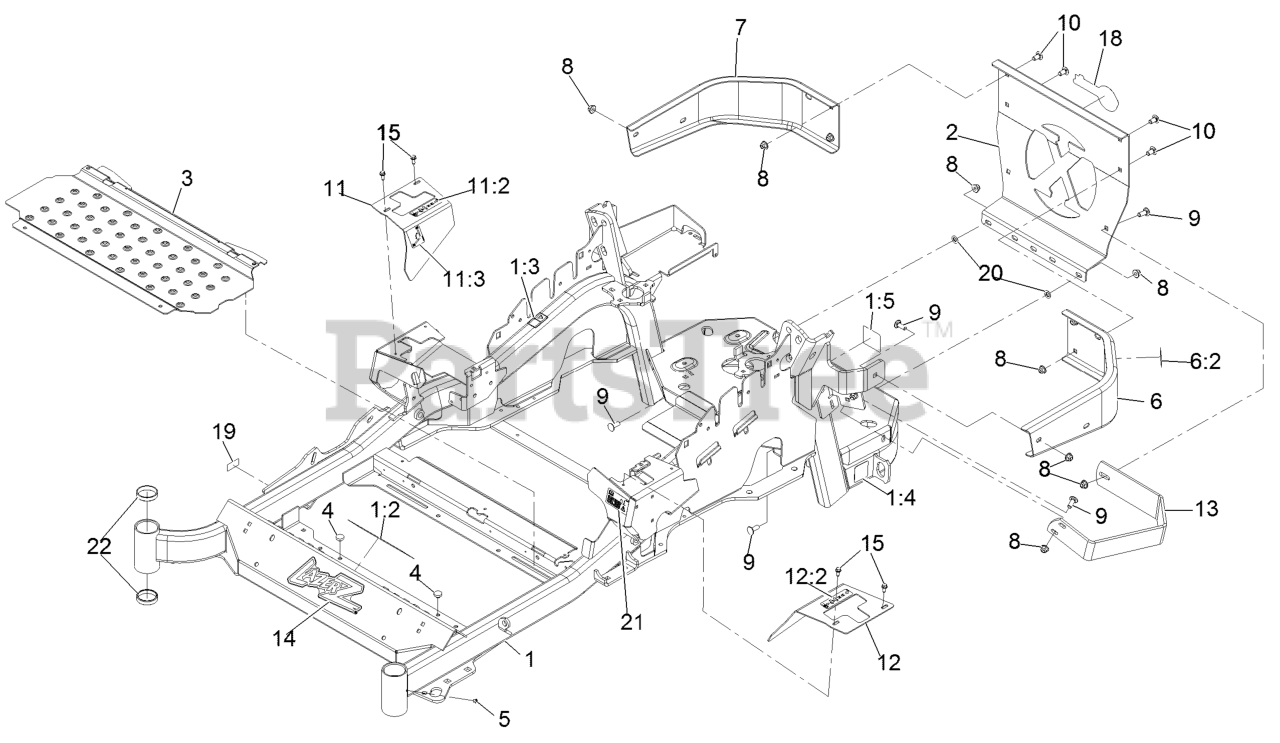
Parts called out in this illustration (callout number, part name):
1	MAINFRAME ASM
1:2	DECAL-WARNING, SLOPE
1:3	DECAL-WARNING
1:4	DECAL-HAZARD, PINCHED FINGER
1:5	DECAL-SPARK ARRESTER
2	PLATE,REAR GUARD
6	LH BUMPER ASM
6:2	DECAL-WARNING
7	BUMPER-RH
8	NUT-HF, NI
9	SCREW-CARR
10	SCREW-CARR
11	RH MOTION CONTROL COVER ASM
11:2	DECAL-CONTROL, MOTION
11:3	DECAL-PARK BRAKE, CE
12	LH MOTION CONTROL COVER ASM
12:2	DECAL-CONTROL, MOTION
13	GUARD-MUFFLER
14	DECAL,LAZER MODEL
15	SCREW-HWH
19	Decal-Patent Ttco.Com
20	NUT-PUSH
21	DECAL-FUEL FILL, CE
22	CUP-BEARING
